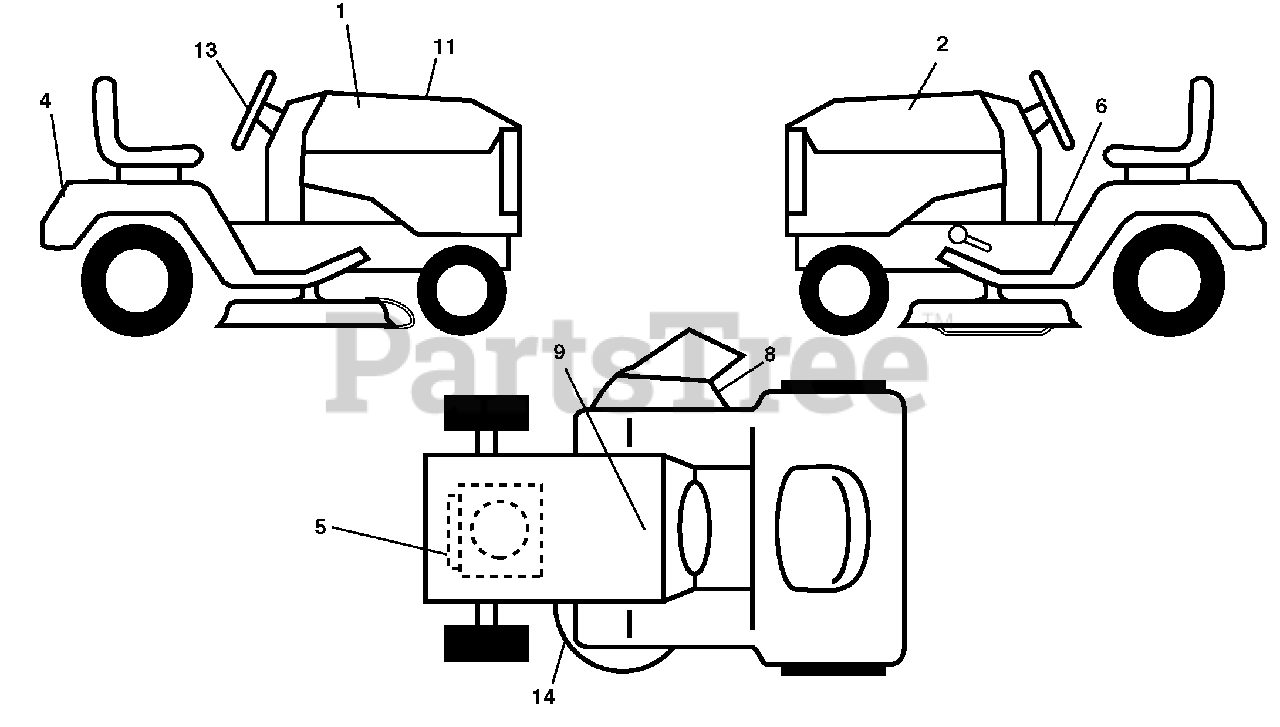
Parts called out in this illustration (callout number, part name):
1	Decal, Hood RH
2	Decal, Hood LH
4	Decal, Fender
5	Decal, Eng. HP
6	Decal, Fender Operator's
8	Decal, Warning
9	Decal, Battery Dnge/Poi
11	Decal, Replacement
13	Decal, Steering Wheel
14	Decal, Mower Schematic
14	Pad, Footrest Control
14	Decal, Bypass
14	Pad, Footrest, LH
14	Manual, Operator's (Eng/French)
14	Manual, Parts (Eng/French)
